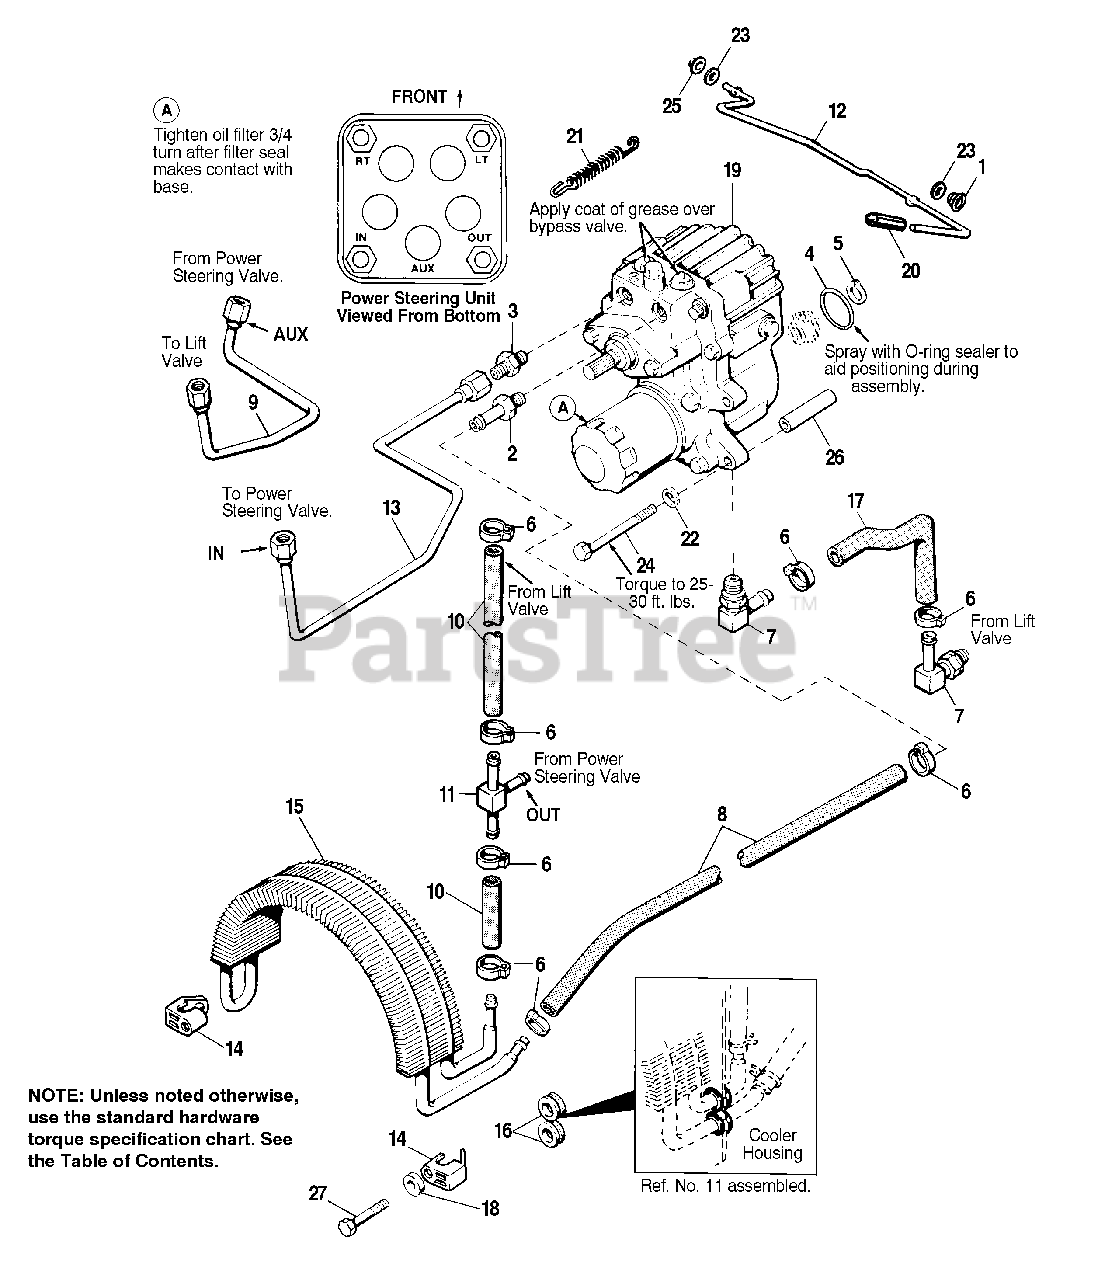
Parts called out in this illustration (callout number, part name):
1	SPRING, Tension, Hydro Release
2	FITTING, Hyd., 9/16-18 O.R. x 1/2
3	FITTING, Hyd., 9/16-18 O.R. x 9/16-18
5	RING, Retaining, External
6	CLAMP, Hose
7	FITTING, Hyd., 7/8-14 O.R. x 5/8, 90 degree
8	HOSE, Hyd., Return
9	TUBE ASSY., Hyd.
10	HOSE, Hyd., Return
11	FITTING, Hyd., Tee, 1/2 x 1/2 x 3/8
12	ROD, Hydrostatic Release
13	TUBE ASSY. Hyd.
14	CLAMP, Oil Cooler
15	COOLER, Oil
16	GROMMET, Rubber
17	HOSE, Hyd., 5/8" I.D., Preformed
19	HYDROSTATIC PUMP
20	GRIP, Release Handle
21	SPRING
22	LOCKWASHER, 3/8
23	WASHER, 17/64 x 5/8 x 3/64
24	CAPSCREW, Hex Hd., 3/8-16 x 4, Gr. 5
25	PUSH NUT
26	SPACER, Mounting
27	SCREW, Plastite, 1/4-20 x 1-1/2
